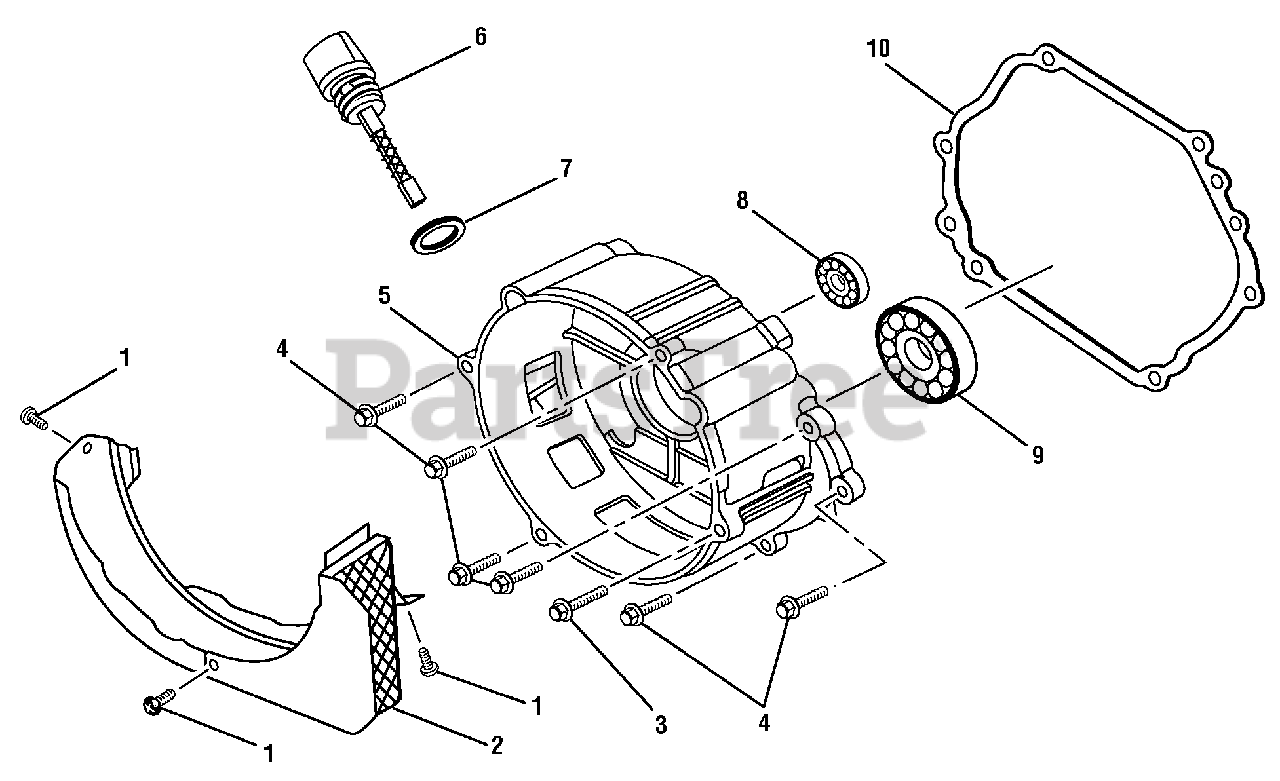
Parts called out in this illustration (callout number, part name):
1	Bolt (M5 x 12 mm, Flange Hd.)
2	Guard Cover (Crankcase)
3	Bolt (M8 X 40 mm)
4	Bolt (M8 X 35 mm)
5	Crankcase Cover Assembly
6	Dipstick Assembly
7	Gasket (Dipstick)
8	Ball Bearing (6202)
9	Ball Bearing (6207)
10	Gasket (Crankcase)
